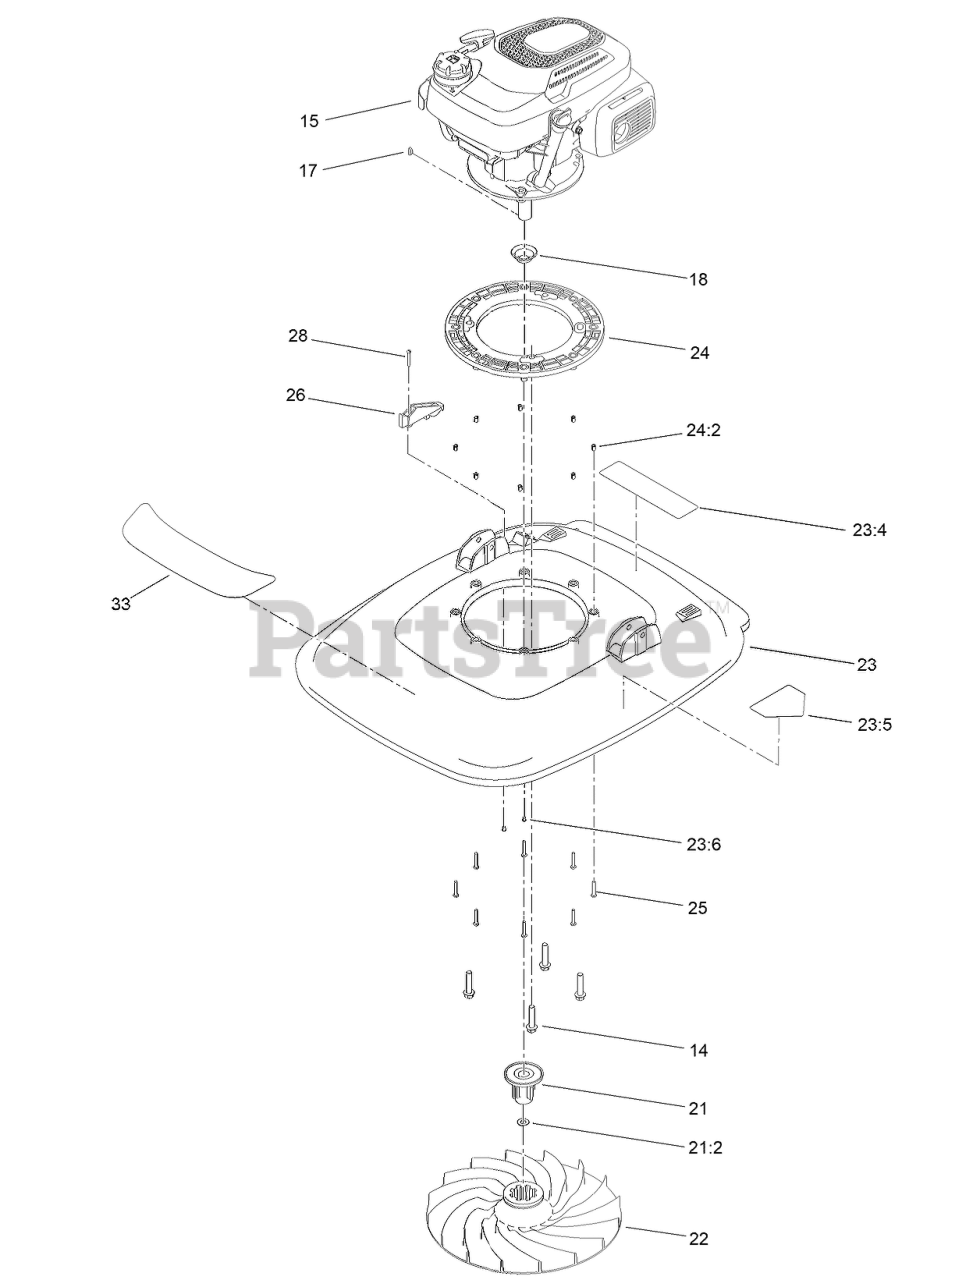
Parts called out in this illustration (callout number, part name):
14	SCREW-TAPTITE
15	ENGINE-HONDA (GCVX170)
17	KEY-WOODRUFF
18	PROTECTOR-SEAL, OIL
21	DRIVE AND SPACER ASM
21:2	WASHER-PLAIN
22	IMPELLER
23	DECK ASM
23:4	DECAL-WARNING
23:5	DECAL-DANGER
23:6	INSERT
24	FRAME-ENGINE
24:2	INSERT-BRASS
25	SET-SCREW
26	BRACKET
28	SCREW
33	DECAL-HOVER PRO
